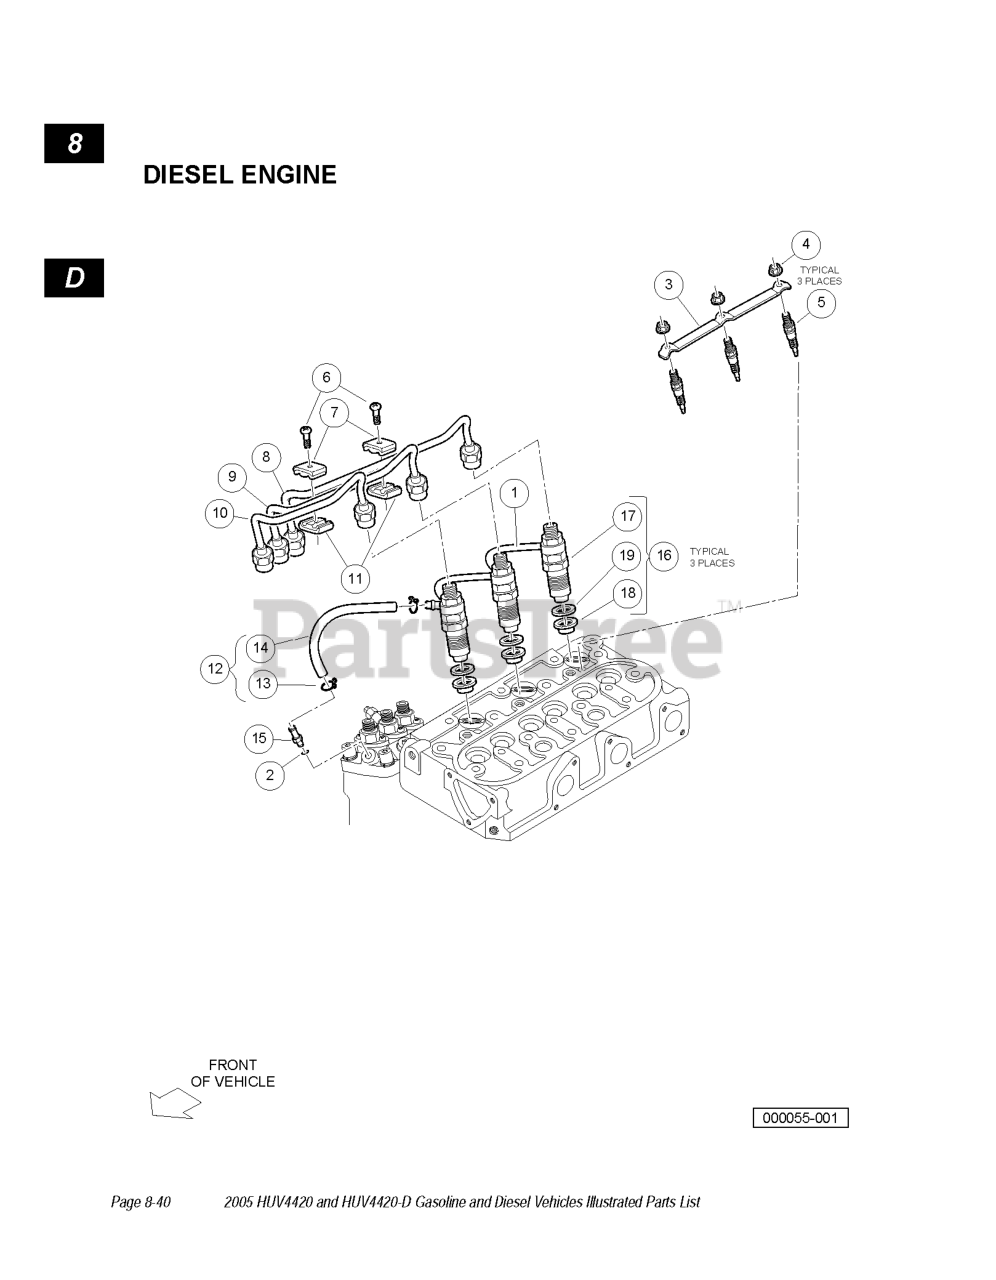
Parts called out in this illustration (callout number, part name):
2	GASKET, 6X10
3	CORD, GLOW PLUG
4	NUT, FLANGE, M4
6	SCREW-WASHER
7	CLAMP, PIPE, TOP
8	PIPE, INJECTION, LEFT
9	PIPE, INJECTION, RIGHT
10	PIPE, INJECTION, MIDDLE
11	CLAMP, PIPE, BOTTOM
12	ASSY PIPE, OVERFLOW
13	CLIP, PIPE, RETURN
15	SCREW, AIR BREEDER
16	KIT, HOLDER, NOZZLE
17	ASSY HOLDER, NOZZLE
18	SEAL, HEAT
19	GASKET, NOZZLE
